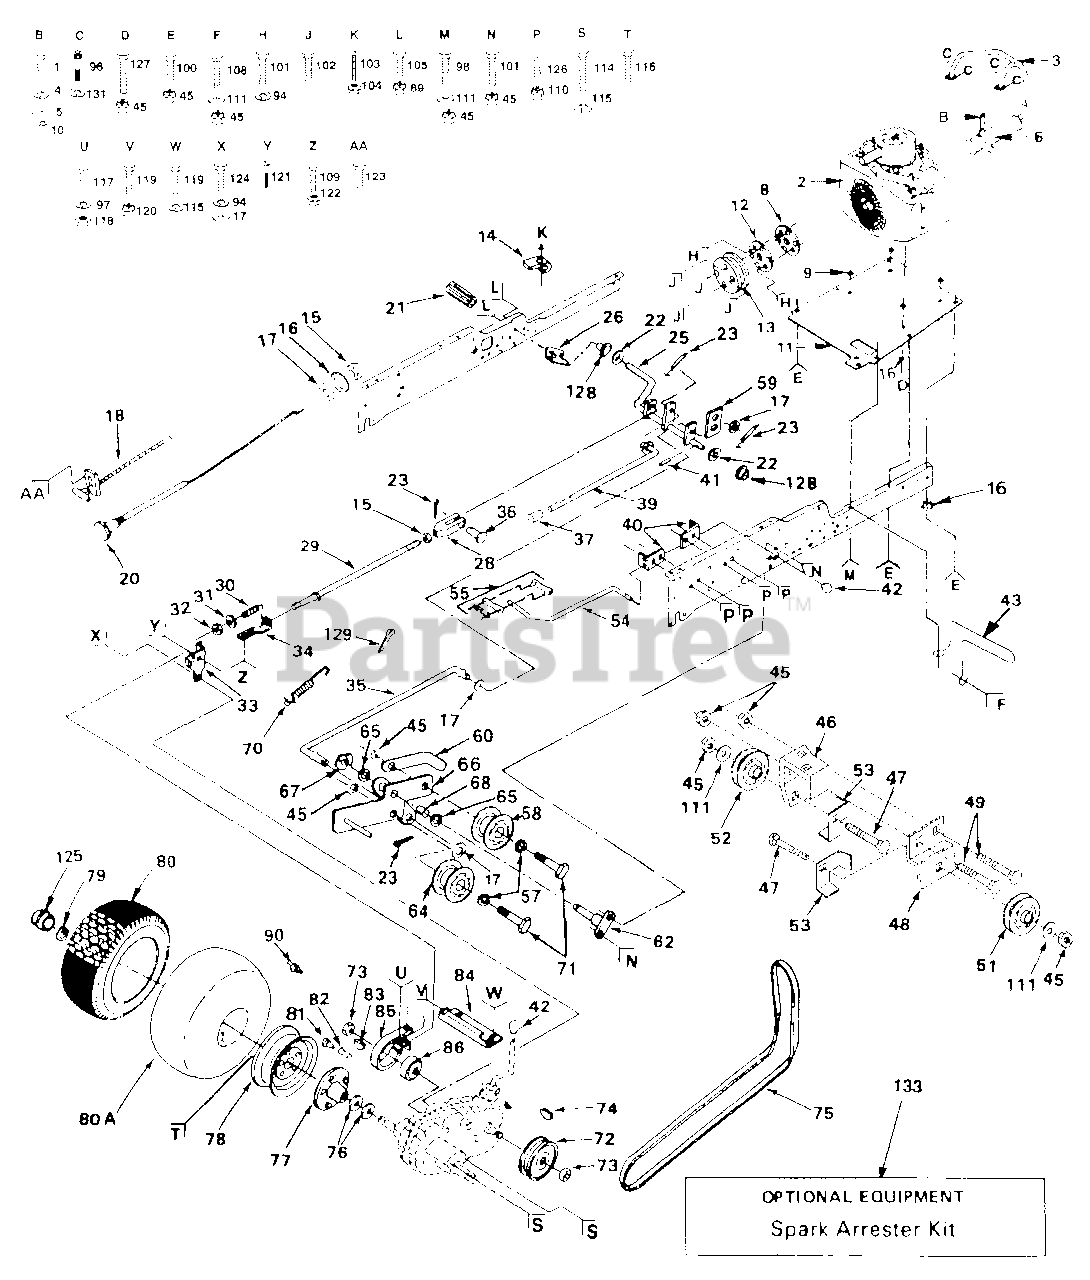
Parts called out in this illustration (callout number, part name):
1	Bolt, Hex Fin 1/4-20 x 3/4 (AYP part number)
2	Engine, 20 HP Kohler, Model No. M20Qs, Type No. 496034
3	Tube Assembly, Exhaust (AYP part number)
4	Washer, Lock Hvy Helical 1/4 (AYP part number)
5	Washer 9/32 x 3/4 x 12 Gauge (AYP part number)
6	Muffler, Exhaust (AYP part number)
8	Chaff Guard (AYP part number)
9	Spacer (AYP part number)
10	Spacer 13/32 x 5/8 x 1/2 (AYP part number)
11	Base, Engine (AYP part number)
12	Adapter (AYP part number)
13	Pulley, Ground Drive (AYP part number)
14	Actuator, Switch, Interlock (AYP part number)
15	Nut, Hex 3/8-24 (AYP part number)
16	Washer, Lock Ext. Tooth 3/8 (AYP part number)
17	Washer 13/32 x 13/16 x 16 Gauge (AYP part number)
18	Control, Throttle
20	Control, Choke
21	Cover, Pedal (AYP part number)
22	Washer 25/32 x 1-1/4 x 16 Gauge (AYP part number)
23	Pin, Cotter 3/32 x 3/4 (AYP part number)
25	Shaft, Foot Pedal (AYP part number)
26	Bracket, Interlock (AYP part number)
28	Yoke (AYP part number)
29	Rod, Brake (AYP part number)
30	Spring, Compression (AYP part number)
31	Washer 13/32 x 1 x 14 Gauge (AYP part number)
32	Nut, Crownlock 3/8-24 (AYP part number)
33	Bracket, Brake (AYP part number)
34	Guide, Rod, Brake (AYP part number)
35	Rod, Clutch (AYP part number)
36	Pin, Clevis (AYP part number)
37	Cap, Plunger (AYP part number)
39	Rod, Parking Brake (AYP part number)
40	Bracket, Rod, Shift (AYP part number)
41	Pin, Roll 3/16 x 1-1/4 (AYP part number)
42	Knob (AYP part number)
43	Muffler, Guard (AYP part number)
45	Nut, Crownlock 3/8-16
46	Bracket, V-Pulley, Drive, Mule (AYP part number)
47	Bolt, Carriage 3/8-16 x 1-3/4 (AYP part number)
48	Bracket, Idler, Flat (AYP part number)
49	Bolt, Carriage 3/8-16 x 3/4 (AYP part number)
51	Idler, Flat (AYP part number)
52	Pulley, Idler (AYP part number)
53	Keeper, Belt (AYP part number)
54	Rod, Shift, Hi - Lo (AYP part number)
55	Clip, Connecting Link, Spring (AYP part number)
57	Washer 13/32 x 7/8 x 13 Gauge (AYP part number)
58	Idler, Flat (AYP part number)
59	Retainer, Spring (AYP part number)
60	Retainer, Belt (AYP part number)
62	Bracket Assembly, Clutch (AYP part number)
64	Idler, Grooved (AYP part number)
65	Washer, Hardened (AYP part number)
66	Bracket, Clutch W/Bearing (AYP part number)
67	Ring, Klip (AYP part number)
68	Bearing, Idler (AYP part number)
70	Spring, Extension (AYP part number)
71	Bolt, Hex 3/8-16 x 1-3/4 (AYP part number)
72	Pulley, Transaxle (AYP part number)
73	Locknut 1/2-20 (AYP part number)
74	Key, Woodruff 3/16 x 5/8 (AYP part number)
75	V-Belt (AYP part number)
76	Washer, Thrust, Axle (AYP part number)
77	Bushing, Assembly and Wheel Hub (AYP part number)
78	Assembly, Rim Rear (AYP part number)
79	Ring, Klip (AYP part number)
80	Tire, Rear (AYP part number)
80A	Tube, Rear (AYP part number)
81	Cap, Valve (AYP part number)
82	Stem, Valve (AYP part number)
83	Key, Woodruff #9 (3/16 x 3/4) (AYP part number)
84	Bracket, Support, Transaxle (AYP part number)
85	Band, Brake (AYP part number)
86	Drum, Brake (AYP part number)
89	Nut, Crownlock 1/4-20 (AYP part number)
90	Fitting, Grease (AYP part number)
94	Washer, Lock 3/8 (AYP part number)
96	Screw, Hex Socket Hd. 5/16-16 x 3/4 (AYP part number)
97	Washer, Lock 1/4 (AYP part number)
98	Bolt, Hex 3/8-16 x 1-1/4 Grade 5 (AYP part number)
100	Bolt, Hex 3/8-16 x 3/4 (AYP part number)
101	Bolt, Hex Head 3/8-16 x 1 Grade 5 (AYP part number)
102	Screw, Hex 5/16-18 x 1 (AYP part number)
103	Screw, Fin #10-24 x 1 (AYP part number)
104	Locknut #10-24 (AYP part number)
105	Bolt, Hex Head 1/4-20 x 3/4 (AYP part number)
108	Bolt, Carriage 3/8-16 x 1-1/4 (AYP part number)
109	Bolt, Carriage 5/16-18 x 3/4 (AYP part number)
110	Nut, Crownlock 5/16-18
111	Washer 13/32 x 1 x 12 Gauge (AYP part number)
114	Bolt, Hex 7/16-14 x 1-1/4 (AYP part number)
115	Washer, Lock 7/16 (AYP part number)
116	Bolt, Hub (AYP part number)
117	Bolt, Carriage 1/4-20 x 5/8 (AYP part number)
118	Nut, Hex 1/4-20 (AYP part number)
119	Bolt, Hex 7/16-14 x 1 (AYP part number)
120	Nut, Crownlock 7/16-14 (AYP part number)
121	Screw, Mach. Udrcut. Flat Head 3/8-16 x 3/4 (AYP part number)
122	Locknut 5/16-18 (AYP part number)
123	Screw, Hex 1/4-20 x 1/2 (AYP part number)
124	Bolt, Hex 3/8-16 x 7/8 (AYP part number)
125	Cap, Axle, Rear (AYP part number)
126	Bolt, Carriage 5/16-18 x 3/4
127	Bolt, Hex 3/8-16 UNC x 1-1/2 (AYP part number)
128	Nyliner (AYP part number)
129	Pin, Cotter 1/4 x 1 (AYP part number)
131	Washer, Lock 5/16 (AYP part number)
133	Kit, Arrester, Spark (AYP part number)
